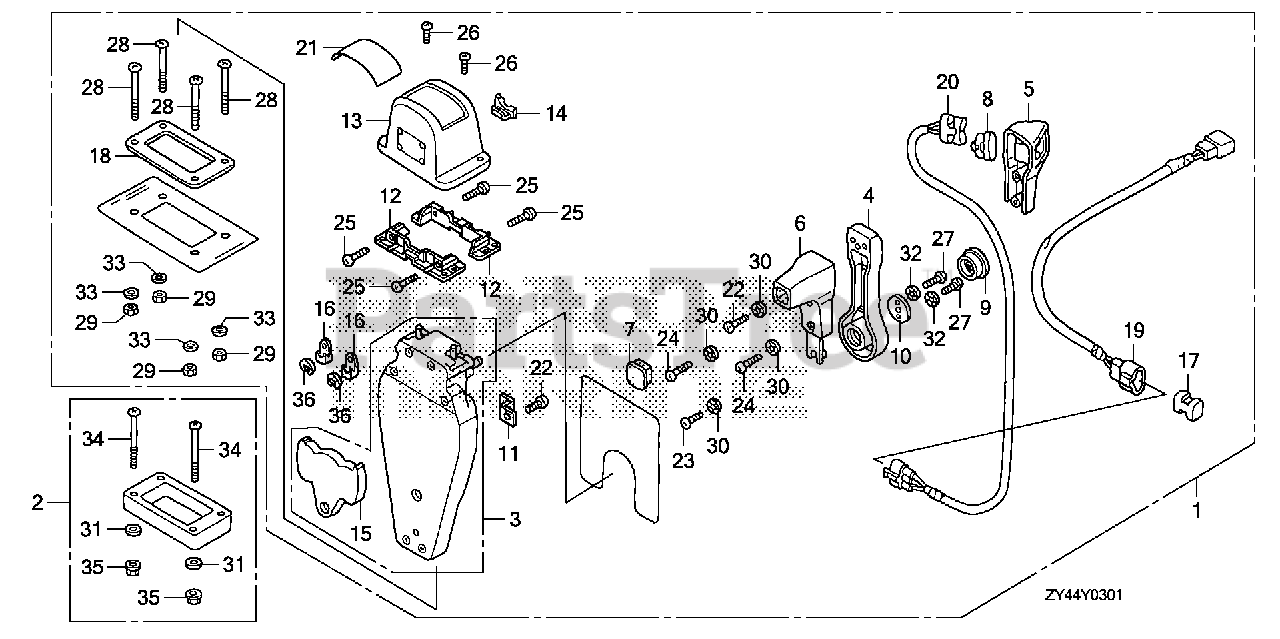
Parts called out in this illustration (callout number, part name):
1	BOX KIT, REMOTE CONTROL (TOP MOUNT SINGLE)(L)
2	SPACER KIT, REMOTE CONTROL BOX (TOP MOUNT SINGLE)
3	HOUSING ASSY., R. (INNER) (TOP MOUNT)
4	HANDLE, REMOTE CONTROL
5	COVER, R. GRIP
6	GRIP, REMOTE CONTROL HANDLE
7	CAP, GRIP
8	CAP, SWITCH
9	BUTTON, THROTTLE
10	PLATE, HANDLE
11	PLATE, CABLE CLAMP
12	BRACKET, REMOTE CONTROL HOUSING
13	HOUSING, REMOTE CONTROL BOX
14	HOUSING, LEAD
15	PLATE, DWELL
16	TERMINAL, CABLE
17	SPACER, CABLE CLAMP
18	GASKET, SINGLE
19	SUB-HARNESS ASSY., POWER TRIM-TILT (B)
20	SWITCH ASSY., POWER TRIM-TILT (B)
21	MARK, REMOTE CONTROL (SINGLE)
22	SCREW, PAN (5X16)
23	SCREW, PAN (5X10)
24	SCREW, PAN (5X20)
25	SCREW, PAN (5X18)
26	SCREW, PAN (4X10)
27	SCREW, PAN (6X18)
28	SCREW, PAN (5X40)
29	NUT, HEX. (5MM)
30	WASHER, LOCK (5MM)
31	WASHER, PLAIN (5MM)
32	WASHER, LOCK (6MM)
33	WASHER, PLAIN (5MM)
34	SCREW, PAN (5X65)
35	NUT, HEX. (5MM)
36	E-RING (6MM)
